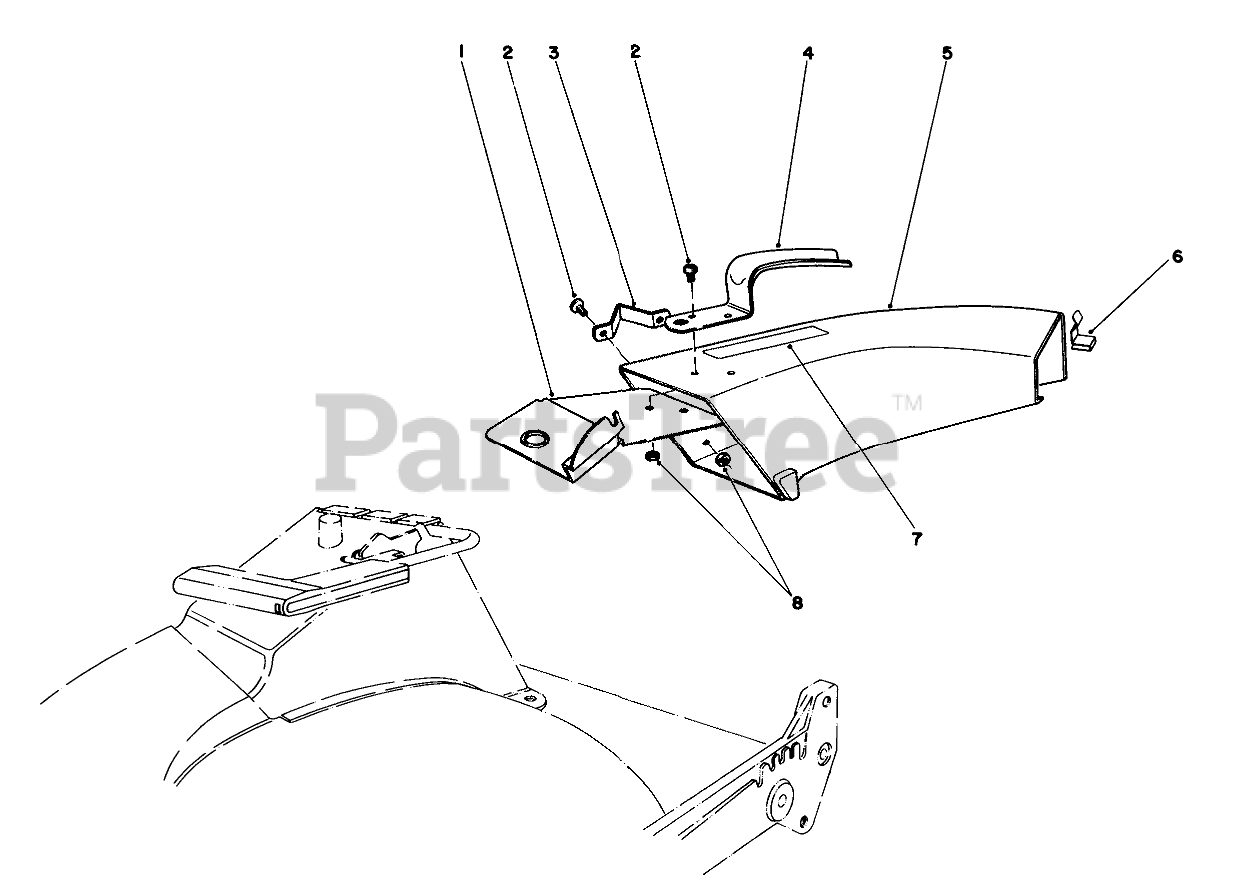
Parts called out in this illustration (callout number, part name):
1	Plate-Discharge Chut
2	10-24 X 5/8 PAN HD MS
3	Bracket
4	CHUTE HANDLE
5	Chute Assembly
6	Clip
7	DECAL CAUTION
8	NUT-LOCK, NI
